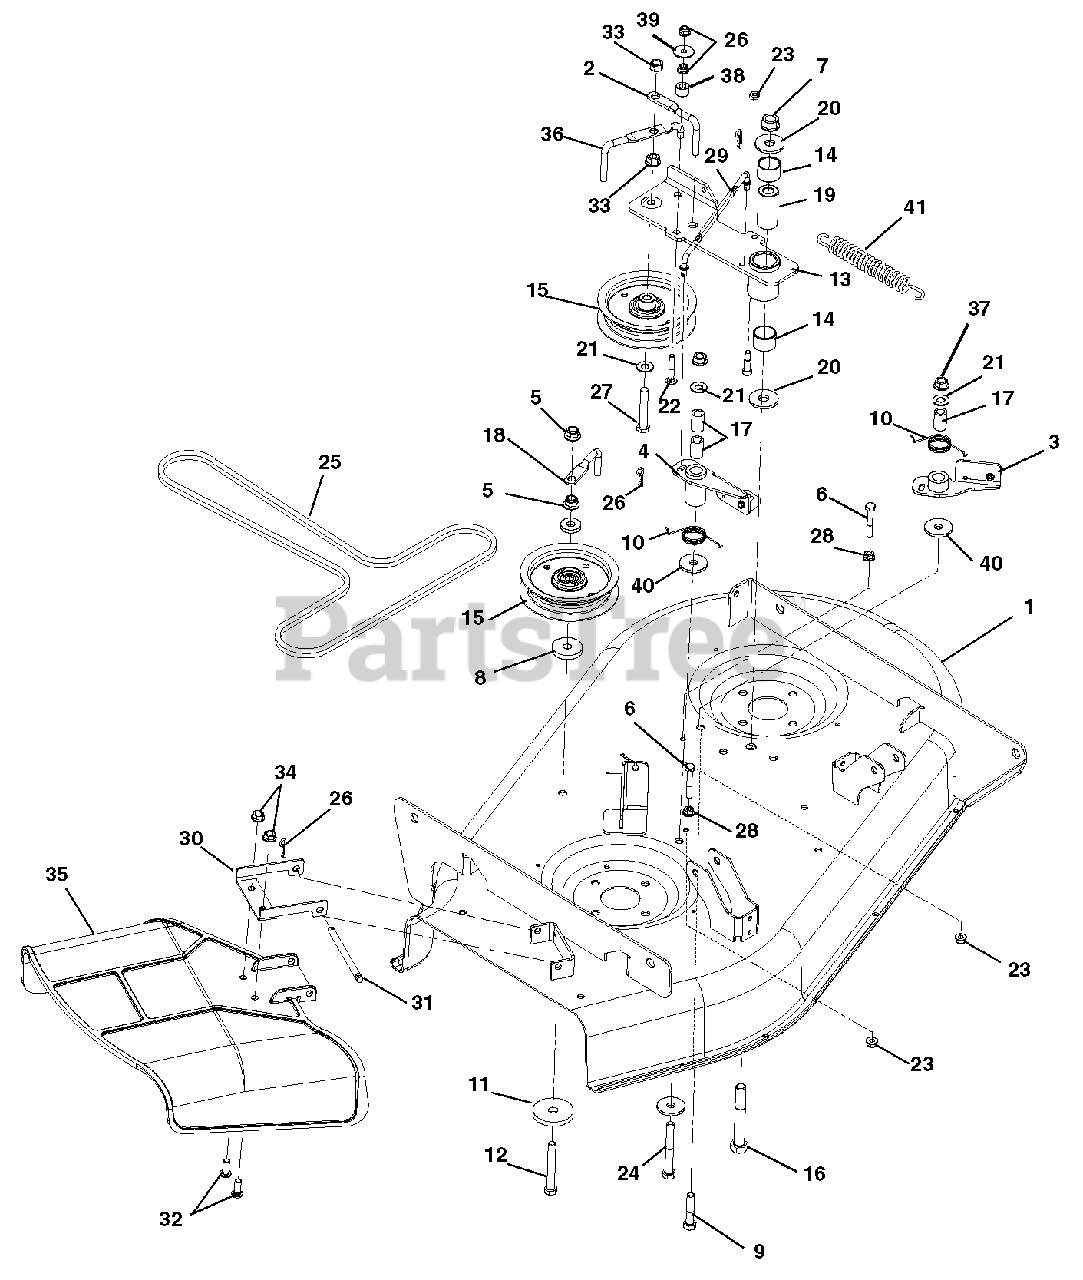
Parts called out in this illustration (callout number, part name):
1	Weldment, 34in Deck
2	Belt Finger
3	Assembly, Brake Arm LH
4	Assembly, Brake Arm RH
5	Nut .38-16 Flange Nyloc
6	Bolt, Hex .25-20 x 1.75 Grade 5
7	Nut, Locking Top Flange .50-13
8	Washer, Flat Steel .406 x 1.50 x .245
9	Bolt, Hex .38-16 x 1.75 Grade 5
10	Spring, Torsion
11	Washer, Flat Steel .469 x 2.00 x .25
12	Bolt, Hex .38-16 x 2.75 Grade 5
13	Idler Arm
14	Bearing, 1.00 x 1.12 x .75
15	Assembly, Idler 4"
16	Bolt, Hex Head .50-13 x 3.50 Grade 5
17	Bushing, Sleeve .391 x .622 x .950
18	Finger, Belt
19	Spacer, Powdered Metal
20	Washer, Flat Steel .511 x 1.44 x 125
21	Washer, Flat Steel .406 x .812 x .065
22	Bolt, Hex Head .25-20 x 1.00 Grade 5
23	Nut, .25-20 Nyloc Flange
24	Bolt, Hex .38-16 x 3.00 Grade 5
25	Belt, HA 98.75 Wrapped
26	Pin, Hair .08 x .18 x 1.18
27	Bolt, Hex .38-16 x 2.25 Grade 5
28	Nut, Locking Flange .250-20
29	Link, Brake
30	Chute Reinforcement
31	Pin, 5/16 x 3.88"
32	Screw, .31-18 x .75
33	Nut, .38-16 Nyloc Flange
34	Nut, Locking Top Flange .31-18
35	Molded Chute
36	Wireform, Belt Finger
37	Nut, Locking Jam .375-16
38	Spacer, .325 x .625 x .455
39	Washer, Flat-Steel .281 x 1.000 x .063
40	Washer, Flat-Steel .406 x 1.375 x .135
41	Spring, Tension .080 x .687 x 5.16
